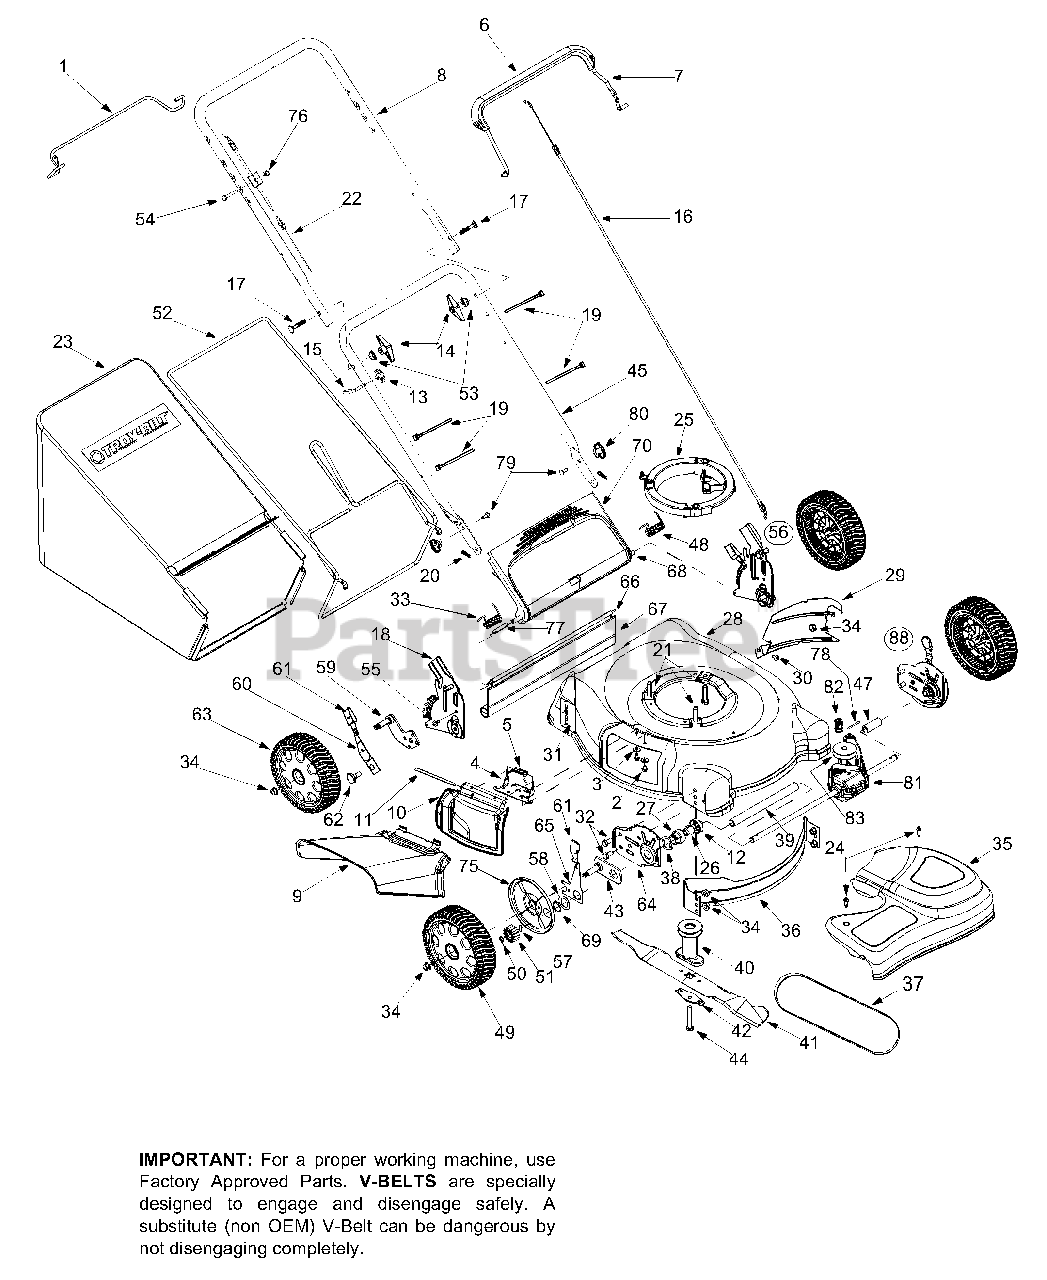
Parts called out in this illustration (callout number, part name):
1	Lower Bail Handle
2	TT Screw 1/4-20 x 0.5
3	Bell Washer.265 x 0.75
4	Deflector Chute Adapter
5	Torsion Spring
6	Deluxe Bail Cover
9	Chute Deflector
10	Mulch Plug Complete
11	Hinge Pin
12	Bearing Retainer
13	Handle Knob
14	Handle Knob
16	Control Cable - 40.75"
17	Carriage Bolt 5/16-18 x 2.0
18	RH Handle Bracket
18	LH Handle Bracket
19	Cable Tie
20	Cotter Pin
21	Self-Tapping Sems Screw
22	Drive Cable
23	Grassbag Assembly
24	Shoulder Screw # 12 -24
25	Engine Spacer
26	Bearing Sleeve
27	Bearing Support
30	Screw AB: 1/4-14:.625
32	Hex Screw 3/8-16 x.75
33	Torsion Spring RH
34	Flange Lock Nut 3/8-16
35	Transmission Cover (Black)
38	Wave Washer
39	Sleeve Spacer 9.04" Lg.
40	Blade Adapter w/ Pulley
41	21" Mulching Blade
42	Blade Bell Support
43	Pivot Plate Assembly
44	Hex Screw 3/8-24 x 2.50
47	Slev. Spacer 2.1" Lg.
48	Torsion Spring LH
49	Wheel 8 x 2.125
50	Snap Ring
51	Gear 14T RH FWD
51	Gear 14T LH FWD
53	Saddle Washer
54	Hex Screw 1/4-20 x 1.50
55	TT Scr. w/Washer 1/4-20 x.625
56	RH Handle Bracket Assembly
56	LH Handle Bracket Assembly
57	Dowel Pin
59	Pivot Arm Assembly - RH
59	Pivot Arm Assembly - LH
60	Rear Spring Lever
61	Spring Lever Knob
62	Shoulder Scr.500 Dia. x.434
63	Wheel, 8 x 2
65	Front Lever - LH
66	Wire
67	Rear Trailing Shield
68	Pivot Rod
69	Snap Ring
70	Rear Discharge Door
75	Wheel Dust Cap
76	Hex Lock Nut 1/4-20
77	Spacer.375 x.50 x 1.02" Lg.
79	Carriage Bolt 1/4-20
80	Wing Nut
81	Transmission Assembly
82	Belt Tension Spring
83	Input Pulley
88	Height Adjustment Assembly RH
88	Height Adjustment Assembly LH
